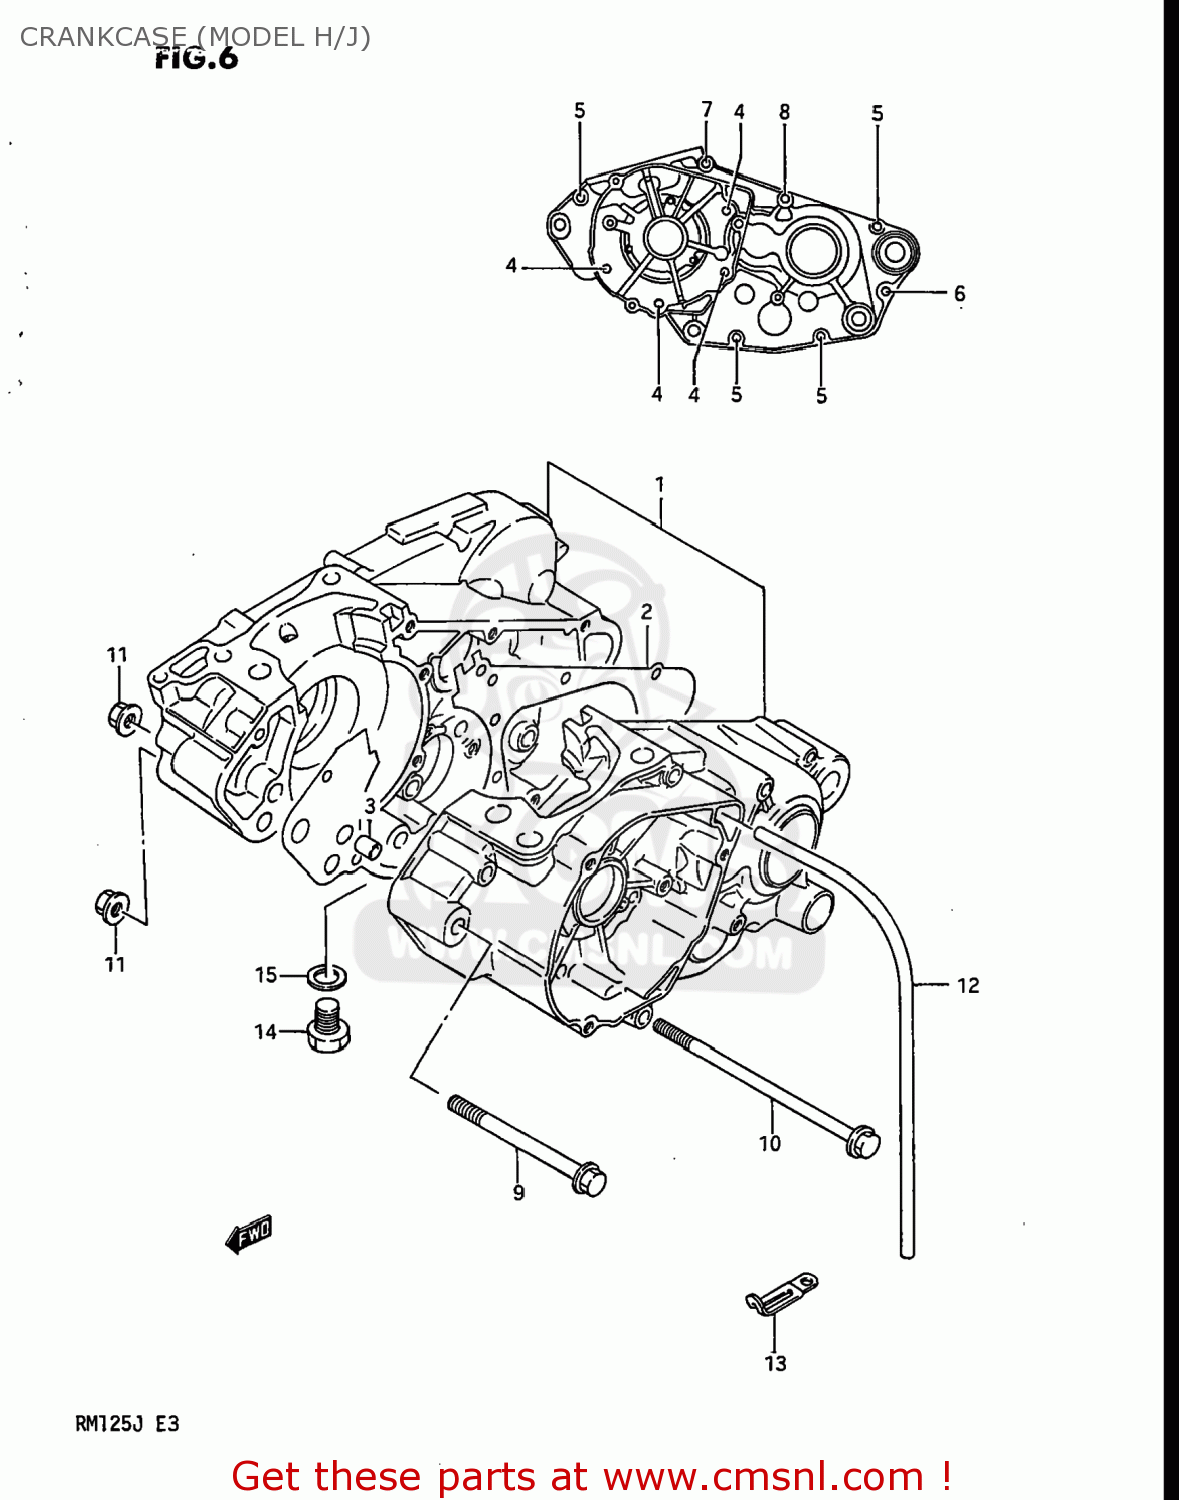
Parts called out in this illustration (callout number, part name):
1	CRANKCASE SET
2	GASKET,CRANKCASE (MCA)
3	PIN
4	SCREW
5	SCREW
6	SCREW 6X60
7	SCREW 6X70
8	SCREW 6X80
9	BOLT(8X95)
10	BOLT(8X150)
11	NUT
12	HOSE
13	CLAMP
14	PLUG
15	GASKET(14X19.2X2) (NAS)
